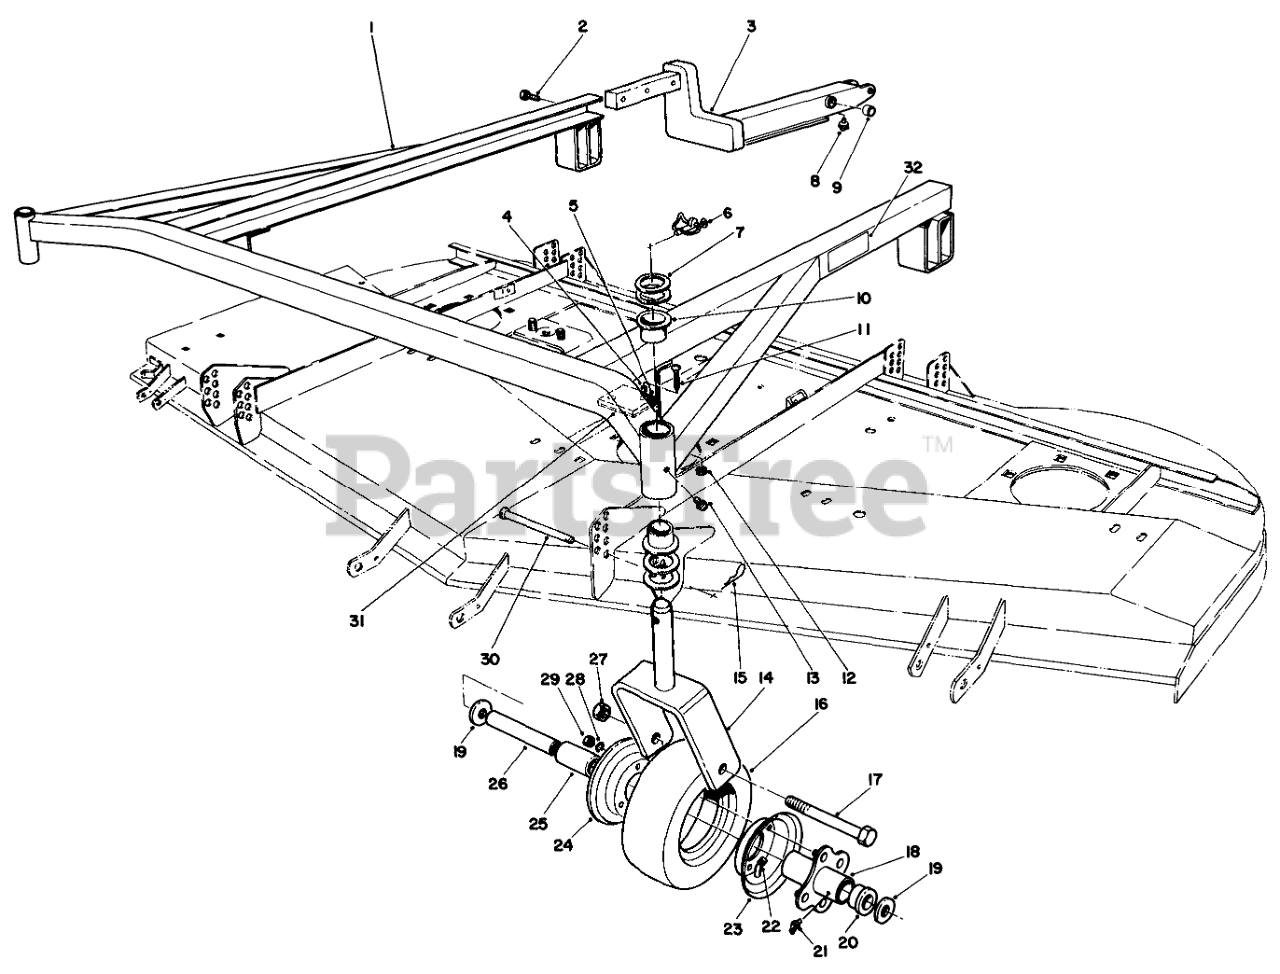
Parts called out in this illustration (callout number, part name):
1	Carrier Frame (Incl. Ref. #10)
2	SCREW-HH
3	Lift Arm-R.H. (Incl. Ref. #8-9)
4	SPACER
5	CUSHION-RUBBER
6	PIN-LYNCH
7	WASHER-THRUST
8	FITTING-GREASE, 90 DEG
9	7/8 ID X 1.128 X 7/8 LG BSHG
10	Bushing
12	NUT-LOCK, NI
13	FITTING-GREASE
14	Castor Fork
15	PIN-HAIR
17	SCREW-HH
18	HUB-CENTER
19	WASHER-FLAT
20	BEARING-OUTSIDE
21	FITTING-GREASE
22	TUBE-INNER (W/VALVE)
23	FEMALE WHEEL HALF
24	MALE WHEEL HALF
25	BEARING-ROLLER
26	SPANNER-TIRE
27	NUT-HEX
28	WASHER-LOCK
29	NUT-HEX
30	PIN-CLEVIS
31	SHIM-CUSHION
32	DECAL-HOC, LH
